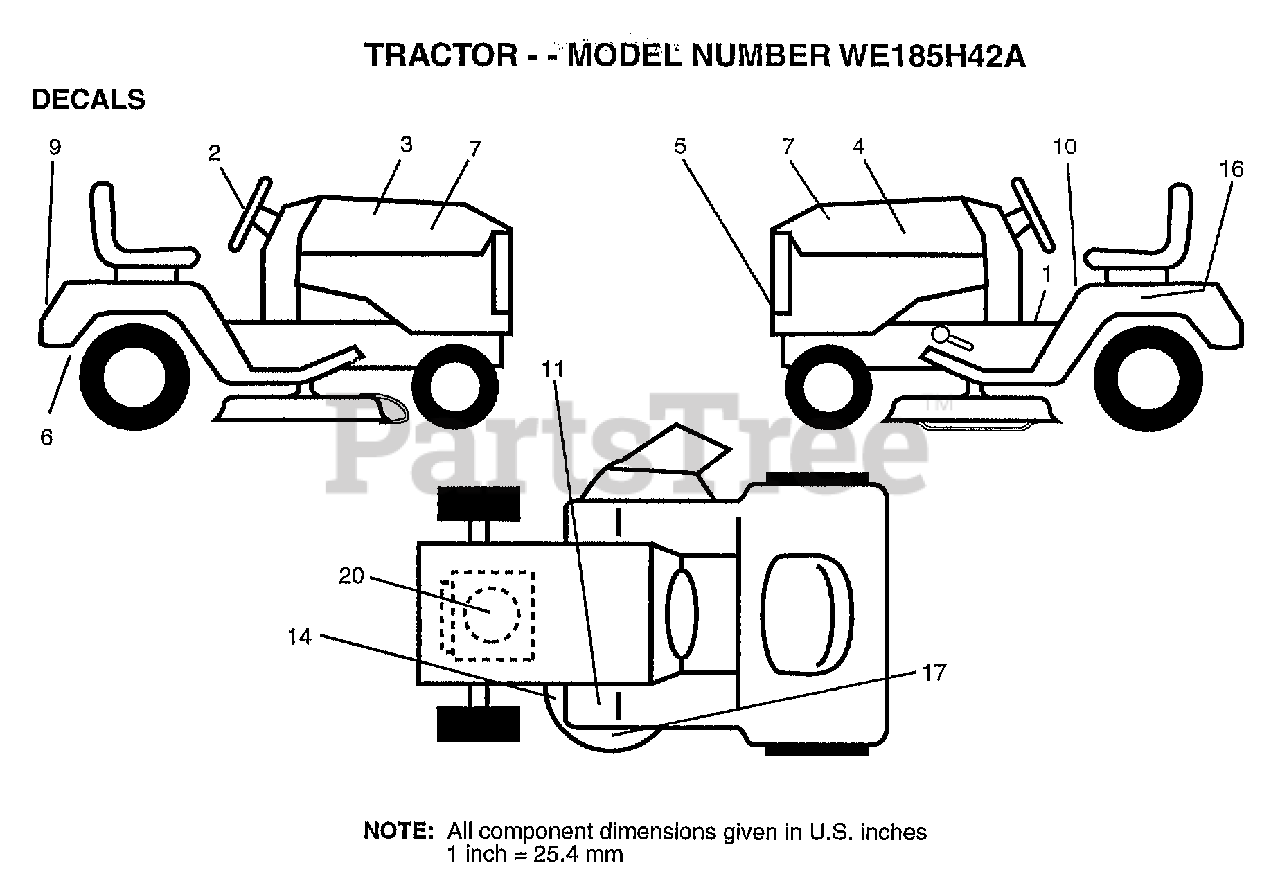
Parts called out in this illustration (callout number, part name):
1	"DECAL INST,SADDLE"
2	"DECAL INS,STRG WH"
3	"DECAL HOOD,RH"
4	DECAL HOOD LH
5	"DECAL GRILLE,LENS"
6	DECAL DRAWBAR LH
7	DECAL PANEL SIDE
9	DECAL-FENDER
10	"DECAL DANGER,FEND"
14	DECAL
16	DECAL.BATRY.3-3908
20	DECAL, HP, ENGINE
